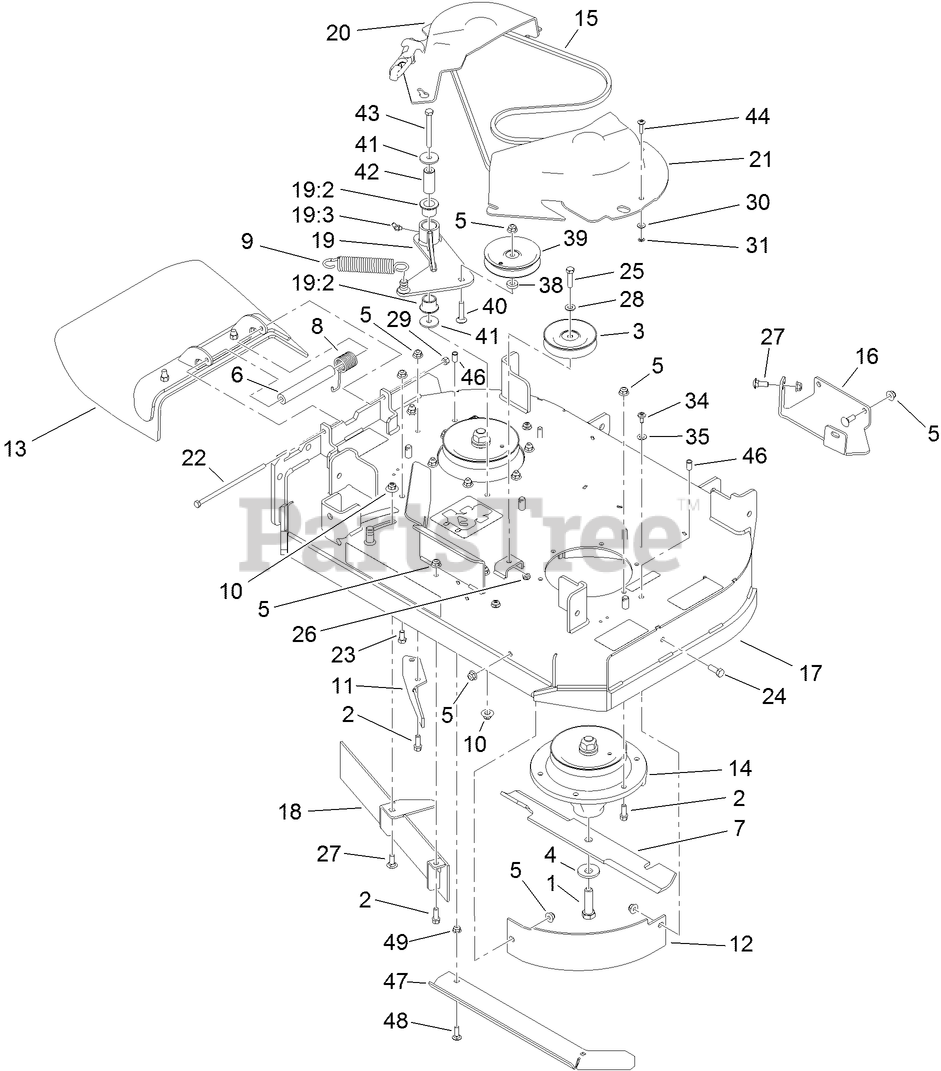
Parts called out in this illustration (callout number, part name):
1	SCREW-BLADE
2	SCREW-HWH
3	PULLEY-IDLER
4	Washer-Blade Bolt, Heavy
5	NUT-HF, NI
6	SPACER
7	BLADE-18IN, HI FLOW
8	SPRING-TORSION
9	SPRING-EXTENSION
10	NUT-FLANGE, NI
11	BAFFLE-DISCHARGE
12	BAFFLE-FRONT, LH
13	DEFLECTOR ASM
14	SPINDLE ASM
15	BELT-V
16	PLATE-SKID
17	DECK ASM
18	FRONT BAFFLE ASM
19	IDLER ARM ASM
19:2	BUSHING
19:3	FITTING-LUBE, 45 DEG
20	COVER-BELT, RH
21	COVER-BELT, LH
22	SCREW-HH
23	SCREW-HH
24	SCREW-HH
25	SCREW-HH
26	NUT-LOCK, NI
27	BOLT-CARR
28	WASHER-FLAT
29	NUT-LOCK, NI
30	WASHER-FLAT
31	NUT-RETAINER
34	SCREW-SHOULDER
35	WASHER-THRUST
38	SPACER
39	PULLEY-IDLER
40	SCREW-CARR
41	WASHER
42	SPACER-PLAIN
43	SCREW-HH
44	SCREW-TTH
46	INSERT-NUT
47	EXTENDER-DECK
48	BOLT-CARR
49	NUT-HF, NI
